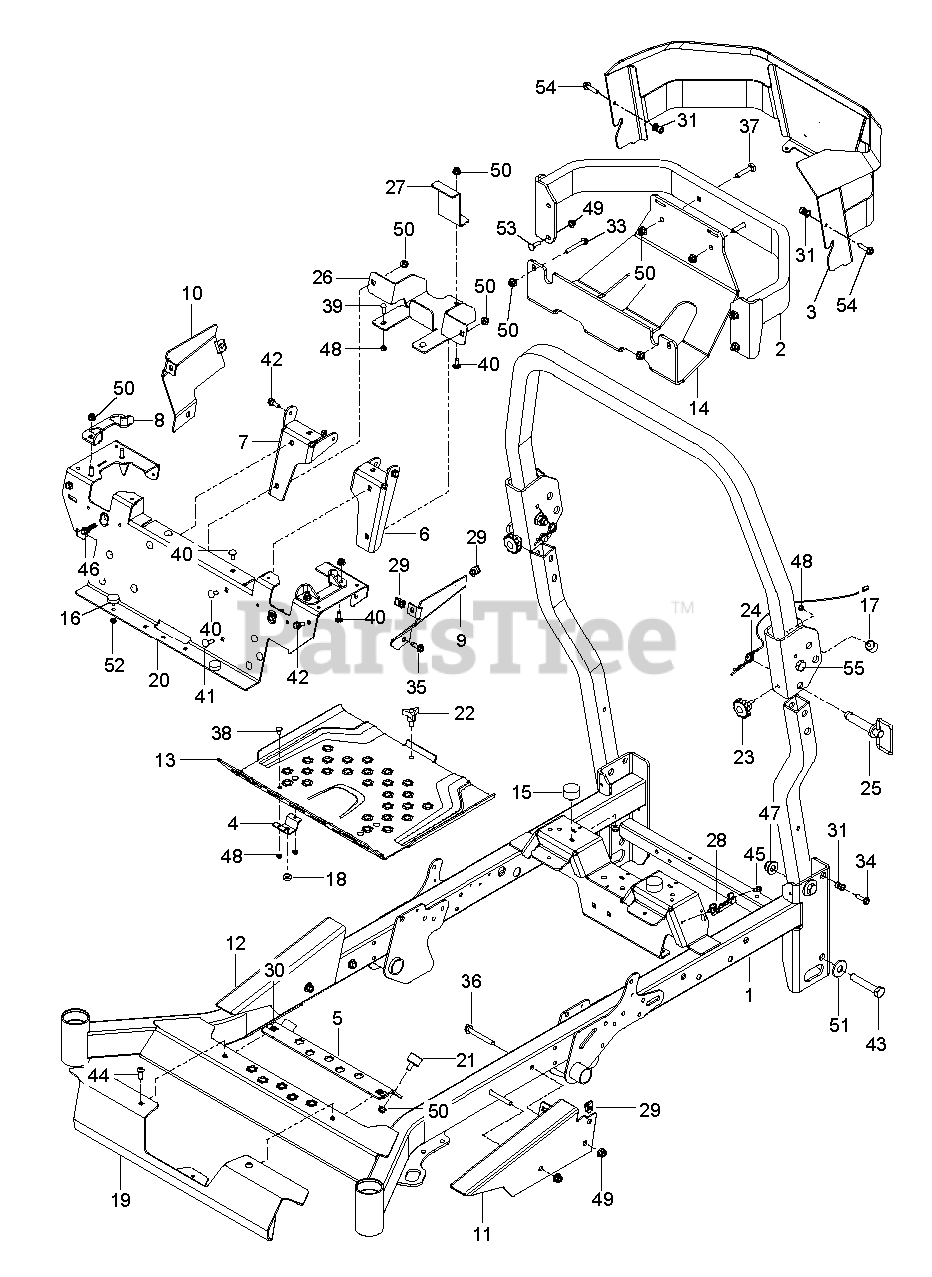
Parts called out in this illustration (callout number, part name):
1	FRAME.W/DECALS.48-60".ORG
2	BUMPER.REAR.ORANGE
2	BUMPER, REAR, ORG
3	GUARD.ENGINE.GREY.498
3	GUARD.PNT.ENGINE.GREY
4	COVER.PNT.VALANCE.PZ.GREY
5	BRACKET.PNT.ISOLATOR.SUPPT.BLK
6	BRACKET.PNT.MTG.SEAT.LH.EDIP
7	BRACKET.PNT.MTG.SEAT.RH.EDIP
8	CABLE.YOKE.PARK.BRAKE
9	PANEL CLOSE OUT LH ORANGE MS-6
10	PANEL CLOSE OUT RH ORANGE MS-6
11	PANEL.PNT.WEDGE.LH.ORG
12	PANEL.PNT.WEDGE.RH.ORG
13	PLATE.PNT.FOOTREST.PZ.ORANGE
14	PLATE SKID, Z500 LONG YAMAHA G
14	PLATE, SKID GRAY
14	PLATE.SKID.GRAY
15	BUMPER 5/16-18
16	BUMPER, 1/4-20 STUD, 1/4
17	BUMPER, MALE STUD, 1/4-20
18	GROMMET, BUMPER
19	COVER.PNT.VALANCE.PZ.GREY
20	CROSS.MEMBER.PNT.SEAT.FRONT.OR
21	ISOLATOR.PZ.FOOTREST
22	KNOB W/STUD
23	KNOB.5/16-18X1"BLACK
24	PIN.HAIR.DOUBLE.LOOP.W/LANYARD
25	PIN.ROPS.W/HANDLE
26	PLATE.PNT.BATTERY.EDIP
27	BRACKET.PNT.MOUNT.BATTERY.EDIP
28	BRACKET.FUSE.RELAY.HOUSING.PZ
29	U-CLIP 5/16-18 NUT RETAINER
30	SCREW.BUTTON.HEAD.TORX.3/8-161
31	NUTSERT 5/16-18 THICK GRIP
33	HHFS 5/16-18 X 2.25 GD 5
34	HHFS 5/16-18 X 1.25 TPBLT GD 5
35	SCREW
35	RP BLT 5/16-18 X 1 THRD FORM D
36	HHFS 3/8-16 X 3 GRD 5 ZD
37	RHSNB 3/8C X 2
39	1/4-20X3/4 CARR BLT
39	BOLT
40	BOLT 5/16C X 3/4" CARRIAGE
41	RHSNB 5/16C X 1
42	BOLT, SHOULDER
43	5/8-11 X 3-1/2 HHB GRADE 5
44	SCREW.BUTTON.HEAD.TORX.3/8-161
45	SCREW
46	SCREW.SHAKEPROOF.1.25.BLACK
47	NUT 5/8-11 FLG NYLOC ZD
48	NUT.1/4-20.HEX.NYLOC.ZD
49	NUT 3/8-16 HEX FLG NYLOC ZD
50	5/16-18 NYLOC FLANGE NUT
51	WASHER, 5/8 FLAT
52	JAM NUT 1/4C (2 2 PW01)
53	BOLT.3/8-14X1.25
54	HHFS 5/16-18 X 1.25 TPBLT GD 5
55	BOLT.HEXAG.5/8-11X4-1/4.G5.ZPY
